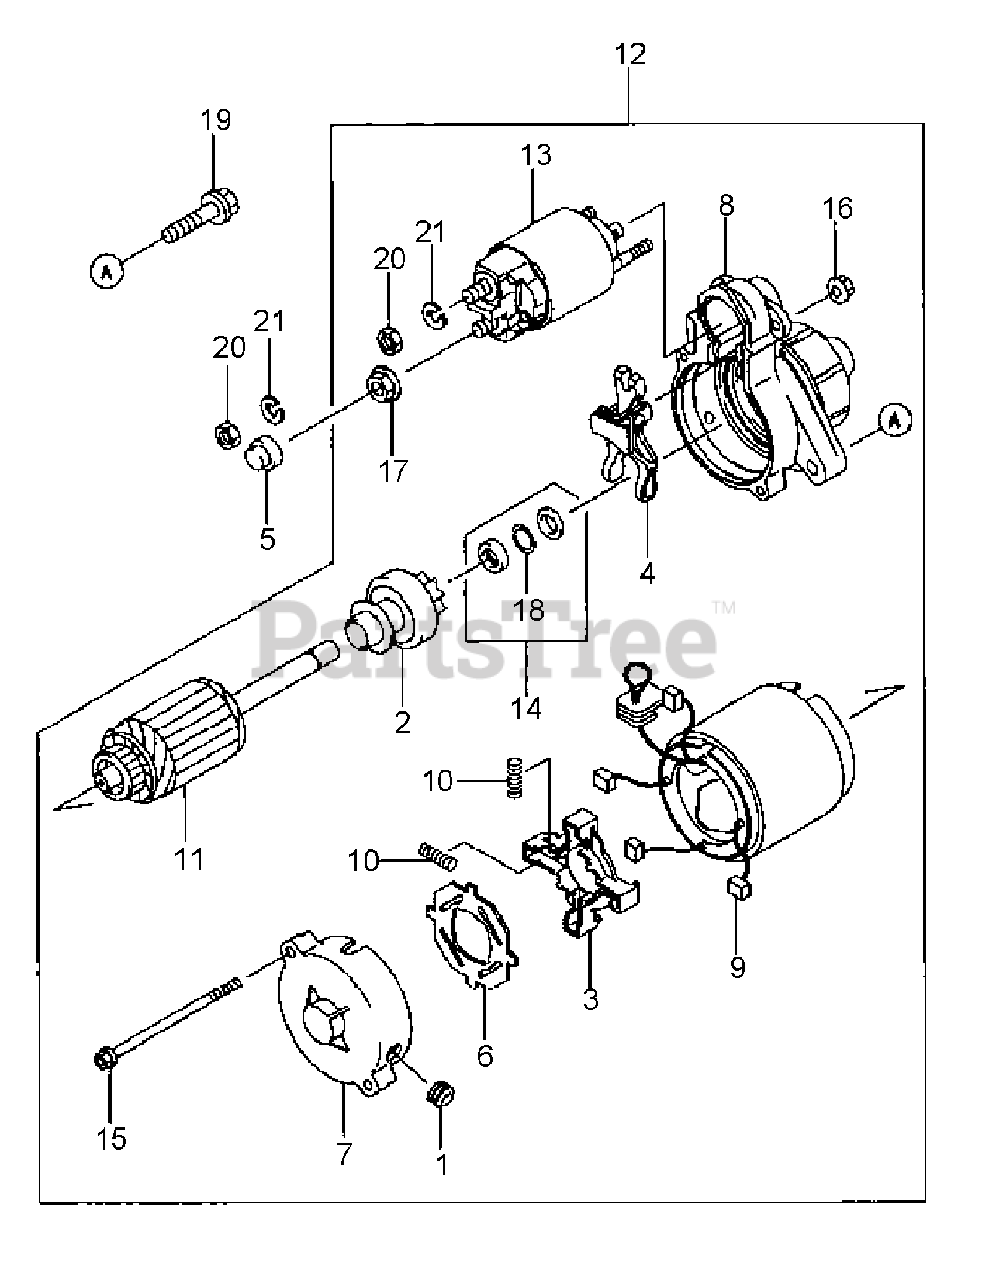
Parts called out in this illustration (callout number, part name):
12	ELECTRIC STARTER
19	FLANGED BOLT
20	HEX NUT SMALL
21	SPRING WASHER
